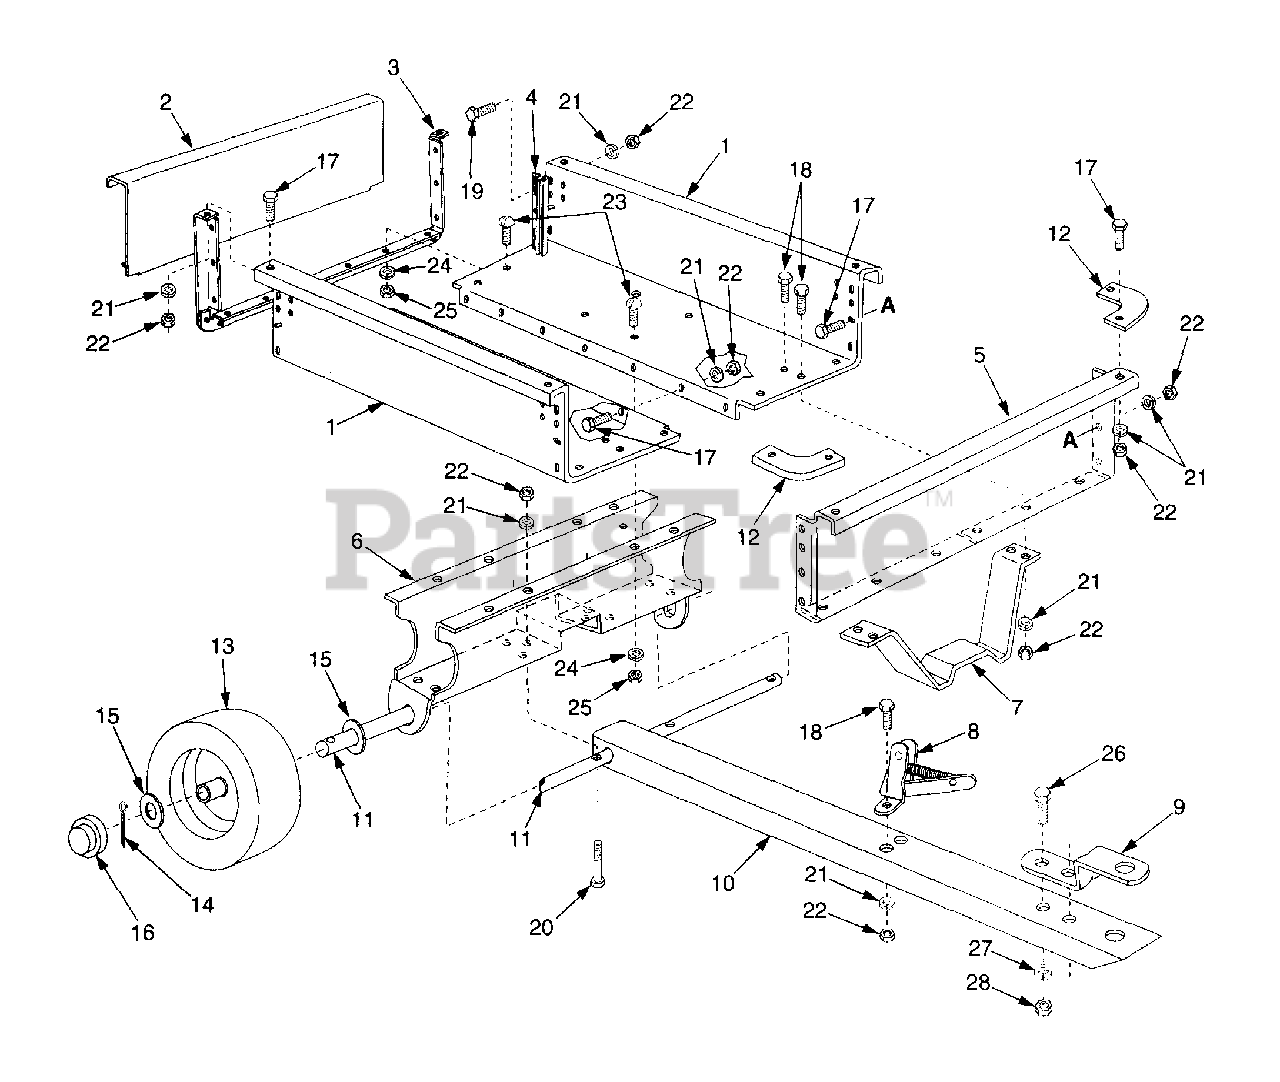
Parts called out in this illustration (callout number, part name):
15	Washer, Flat 1"
16	Hub Cap
17	Hex Bolt, 1/4-20 x 1/2"
18	Hex Bolt, 1/4-20 x 5/8"
19	Hex Bolt, 1/4-20 x 3/4"
20	Hex Bolt, 1/4-20 x 1-3/4"
21	Lock Washer, 1/4"
22	Hex Nut, 1/4-20
23	Slt. Truss Hd.Bolt 5/16-18 x 3/4" Lg.
24	Lock Washer, 5/16"
25	Hex Nut, 5/16-18
26	Hex Bolt, 3/8-16 x 1" Lg.
27	Lock Washer, 3/8"
28	Hex nut, 3/8-16 Thread
